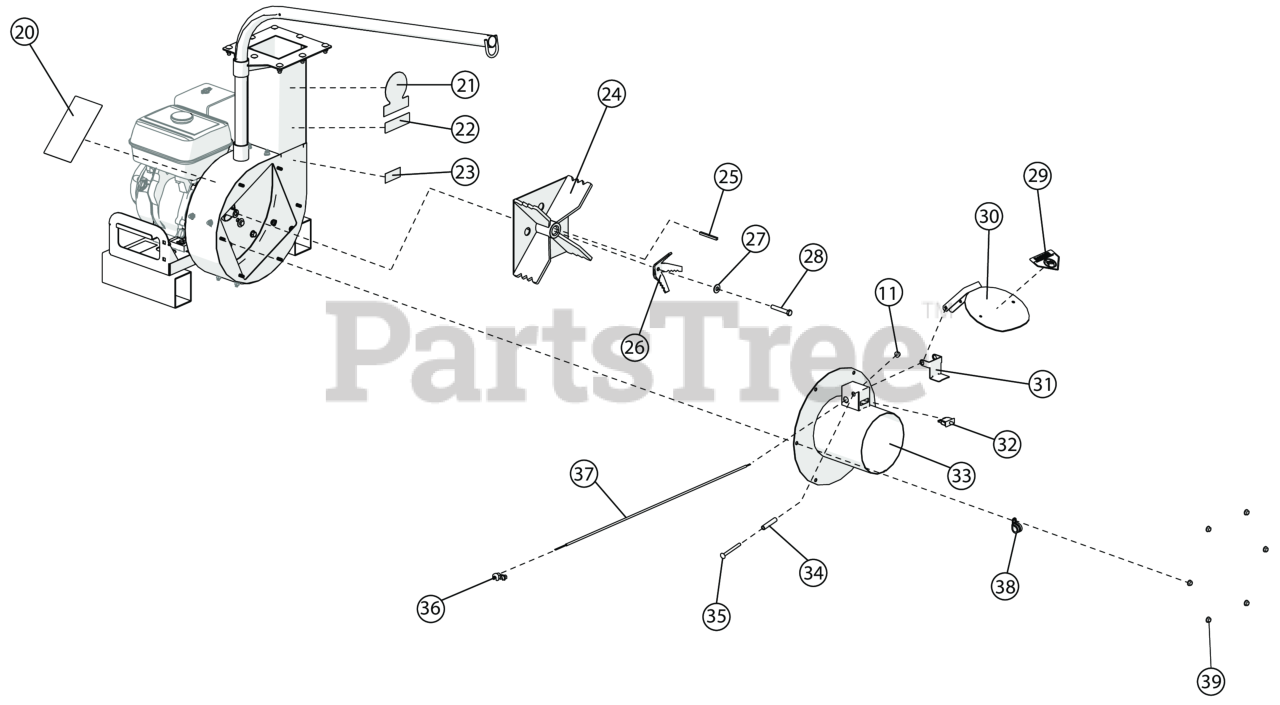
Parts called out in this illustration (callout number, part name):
11	NUT-HEX-NYLK, FLG .3125-18 ZP
20	LABEL QL INSTRUCTION/WARN
21	LABEL LOGO DL12/13/18
22	LABEL DL PIRANHA
23	LABEL, WARNING LINER DL
24	IMPELLER WA DL12/13
25	KEY 1/4" SQ X 2 3/4"
26	DEBRIS REDUCER DL12/13/18
27	WSHR-STL, BLV, .450" X 1.063" X .082" MZ
28	SCREWCAP 7/16"- 20 X 2 3/4" GR. 8 W/PATCH
29	LABEL WARNING OPEI
30	FLAPPER WA 8"
31	LEVER HOSE SWITCH
32	SWITCH, SAFETY INTERLOCK
33	PLATE FRONT WA DL12/13
34	SPACER 3/8" X 2 1/2"
35	BOLT CARRIAGE 5/16"-18 X 3 1/2" ZP
36	STRAIN RELIEF
37	HARNESS WIRE DL 12/13/18 KILL SWITCH
38	CLAMP ROUTING FUEL LINE
39	NUT FLANGE 5/16"-18 ZP
